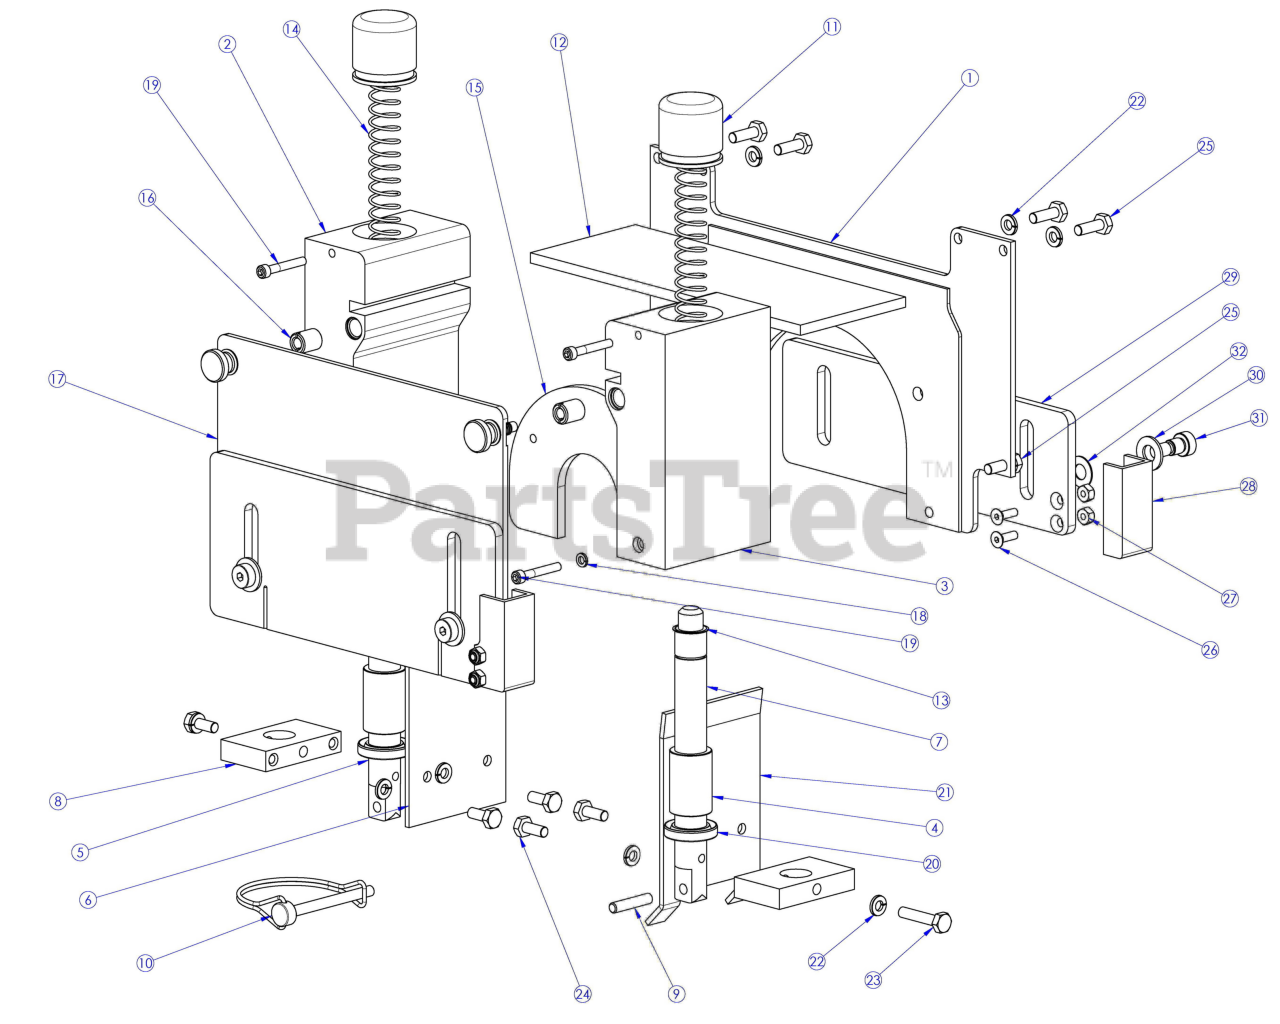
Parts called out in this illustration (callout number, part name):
1	Panel, Rear, Bb
2	Blade Block, Rear
3	Blade Block, Front
4	3/4 Id X 1 Od X 1 1/2 Bushing
5	Shaft, Rear Blade Block, X750
6	Plate, Rear Diverter
7	Shaft, Front Blade Block, X750
8	Block, Shaft Collar, Bb
9	Dowel Pin .250 X 1.25 Steel
10	Snapper Pin, 1/4" X 2 1/2"
11	Cap, Blade Block
12	Top Cover, Bb
13	Snap Ring, Spiral .750"
14	Spring, Bb, X750
15	Cover, Belt Access
16	Insert, 1/2-13 X 5/16-18
17	Blade Block Cover
18	Washer, Split #10 S.S.
19	Shcs 10-32 X 1 1/4 S.S.
20	Dust Seal, 3/4" Shaft
21	Plate, Front Diverter
22	Washer, Split 1/4" S.S.
23	HHB 1/4-20 X 1.25 S.S. All Thrd
24	HHB 1/4-20 X .625 S.S.
25	HHB 1/4-20 X .75 S.S.
26	Fhs, 10-24 X 5/8 S.S.
27	Nut, Nyloc, #10-24 Cad
28	Channel, Inner Diverter
29	Cover, Inner Lexan
30	Washer, 3/8" Flat
31	Shsb, 3/8 X 3/8
32	Washer, 3/8" Delrin
